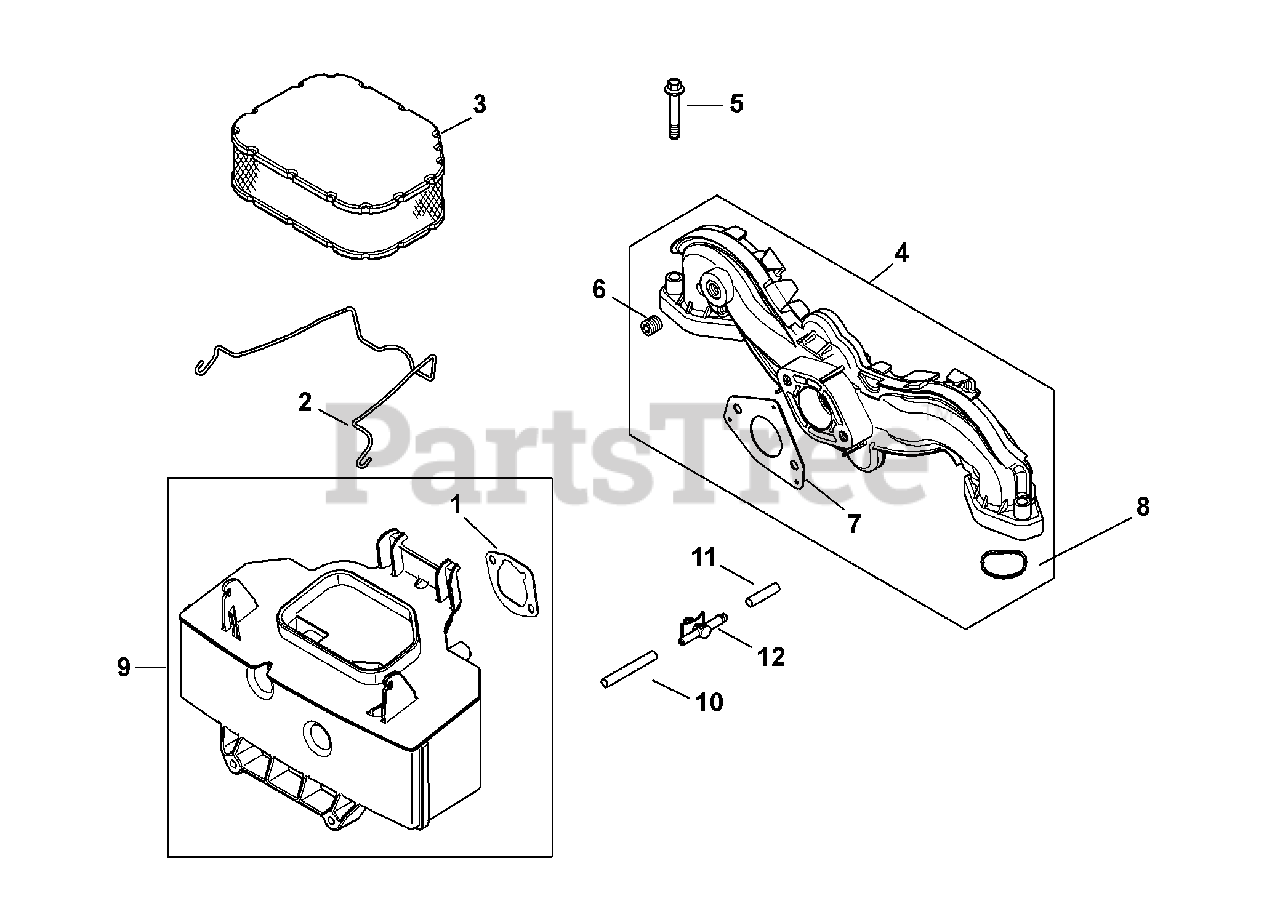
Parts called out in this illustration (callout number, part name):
1	Air Cleaner Base Gasket
2	Air Cleaner Element Latch
3	Air Filter Element
4	Intake Manifold Kit
5	Screw, M6 x 1.0 x 40
6	Pipe Plug, 1/8
7	Carburetor Gasket
8	O-Ring, Intake Port
9	Air Cleaner Base
10	Evaporative Hose, 20"
12	Evaporative Connector
